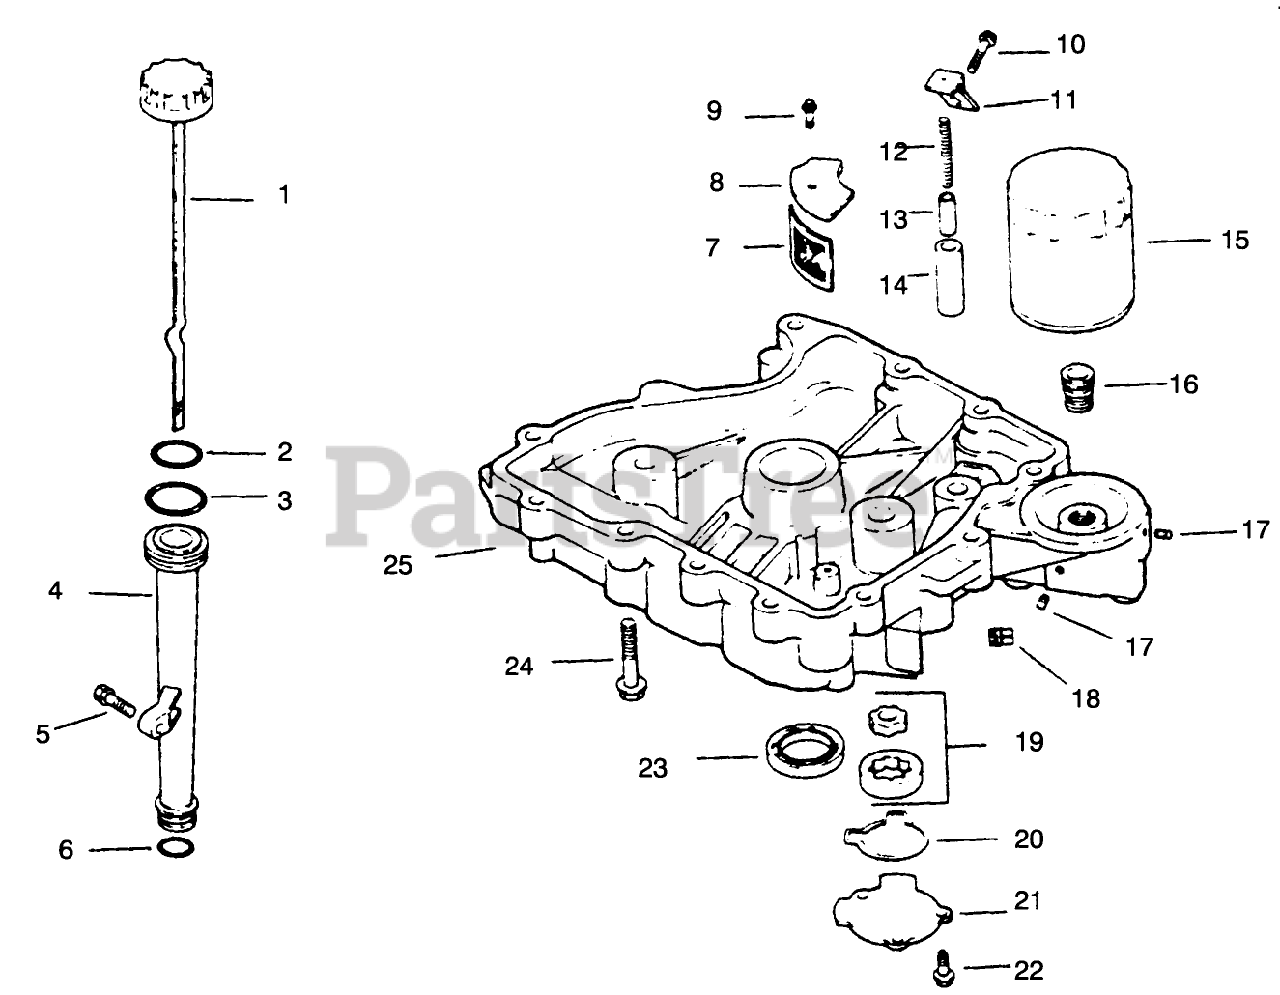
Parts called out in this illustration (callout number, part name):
1	Dipstick INC 2-3 (Only On: 72042, 72063, 72062, 72043)
2	ORing
3	O Ring-Upper Fill Tube (Only On: 72103)
4	Tube-Oil Fill (Only On: 72103, 72083)
6	O-Ring-Lower Fill Tube (Only On: 72042, 72063, 72062, 72043)
7	Screen-Oil Pickup (Only On: 72042, 72063, 72062, 72043)
8	Cover-Oil Pickup Screen (Only On: 72042, 72063, 72062, 72043)
11	Bracket-Oil Pump Relief (Only On: 72042,72043,72062,72063)
12	Spring-Oil Relief Valve (Only On: 72042,72043,72062,72063)
13	Piston-Oil Relief Valve (Only On: 72042, 72063, 72062, 72043)
14	Body-Oil Relief Valve (Only On: 72042, 72063, 72062, 72043)
15	Filter-Oil
16	Adapter-Oil Filler
17	Plug-SH 1/8
19	Pump-Oil (Only On: 72042, 72063, 72062, 72043)
20	O Ring-Oil Pump Cover (Only On: 72042,72043,72062,72063)
21	Cover-Oil Pump (Only On: 72042,72043,72062,72063)
23	Seal-Crankshaft (Only On: 72042, 72043, 72062, 72063)
25	Pan-Oil
